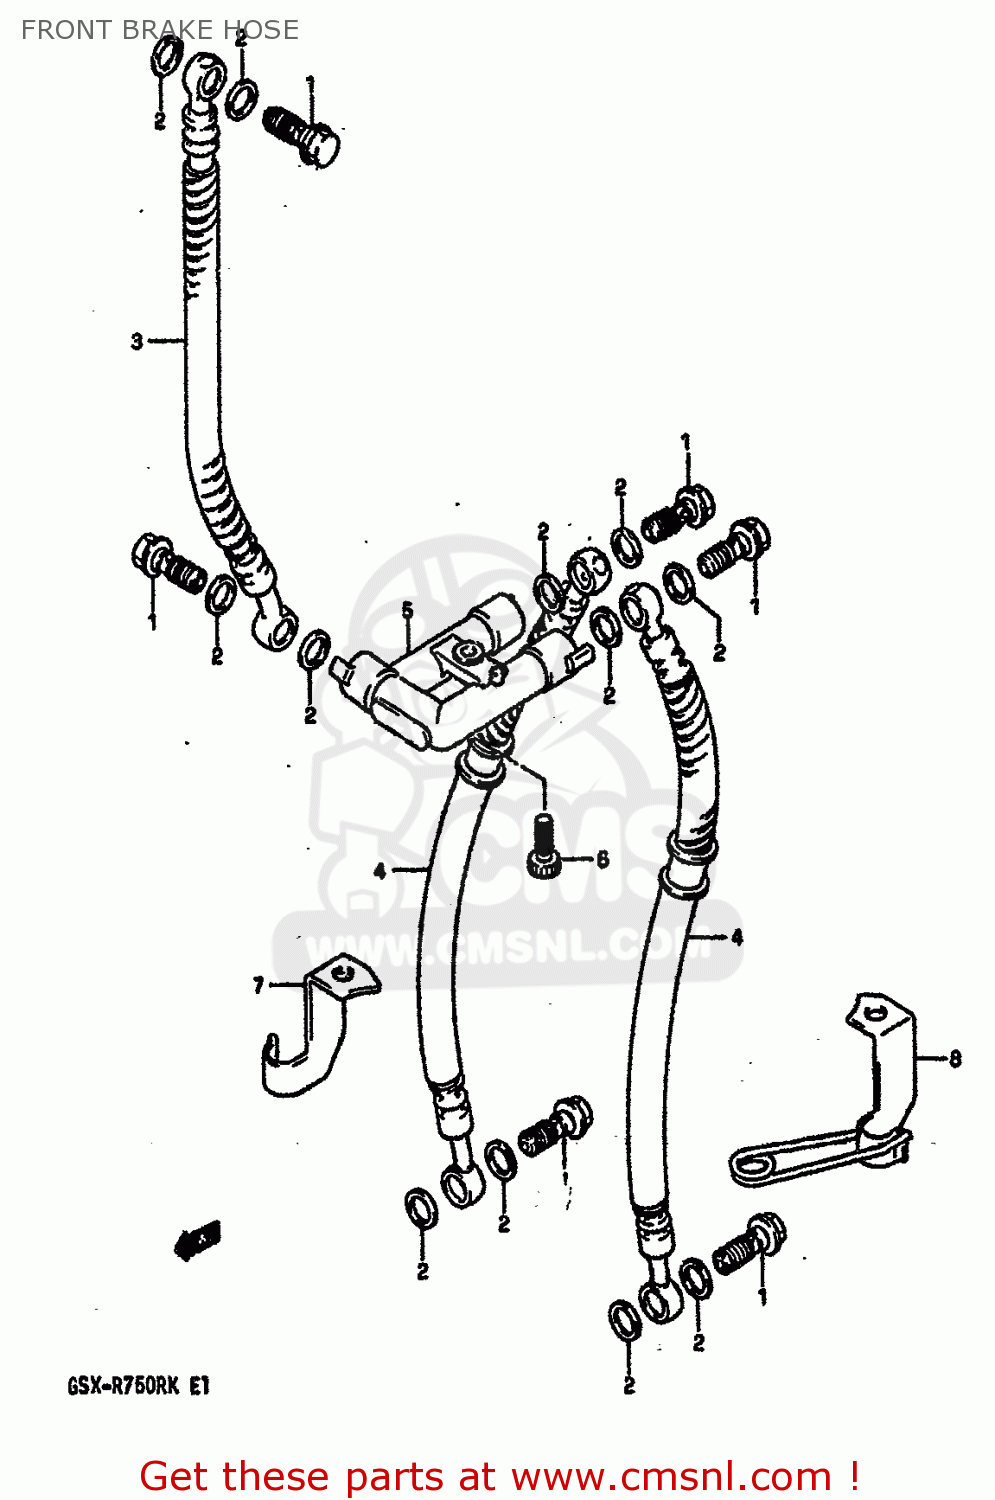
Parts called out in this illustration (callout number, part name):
1	BOLT UNION
2	WASHER(10X15X1.5)
3	HOSE,FRONT BRAKE NO.1
4	HOSE,FRONT BRAKE NO.2
5	JOINT,BRAKE HOSE
6	BOLT
7	CLAMP,FR BRAKE HOSE,R
8	CLAMP COMP,FRONT BRAKE
